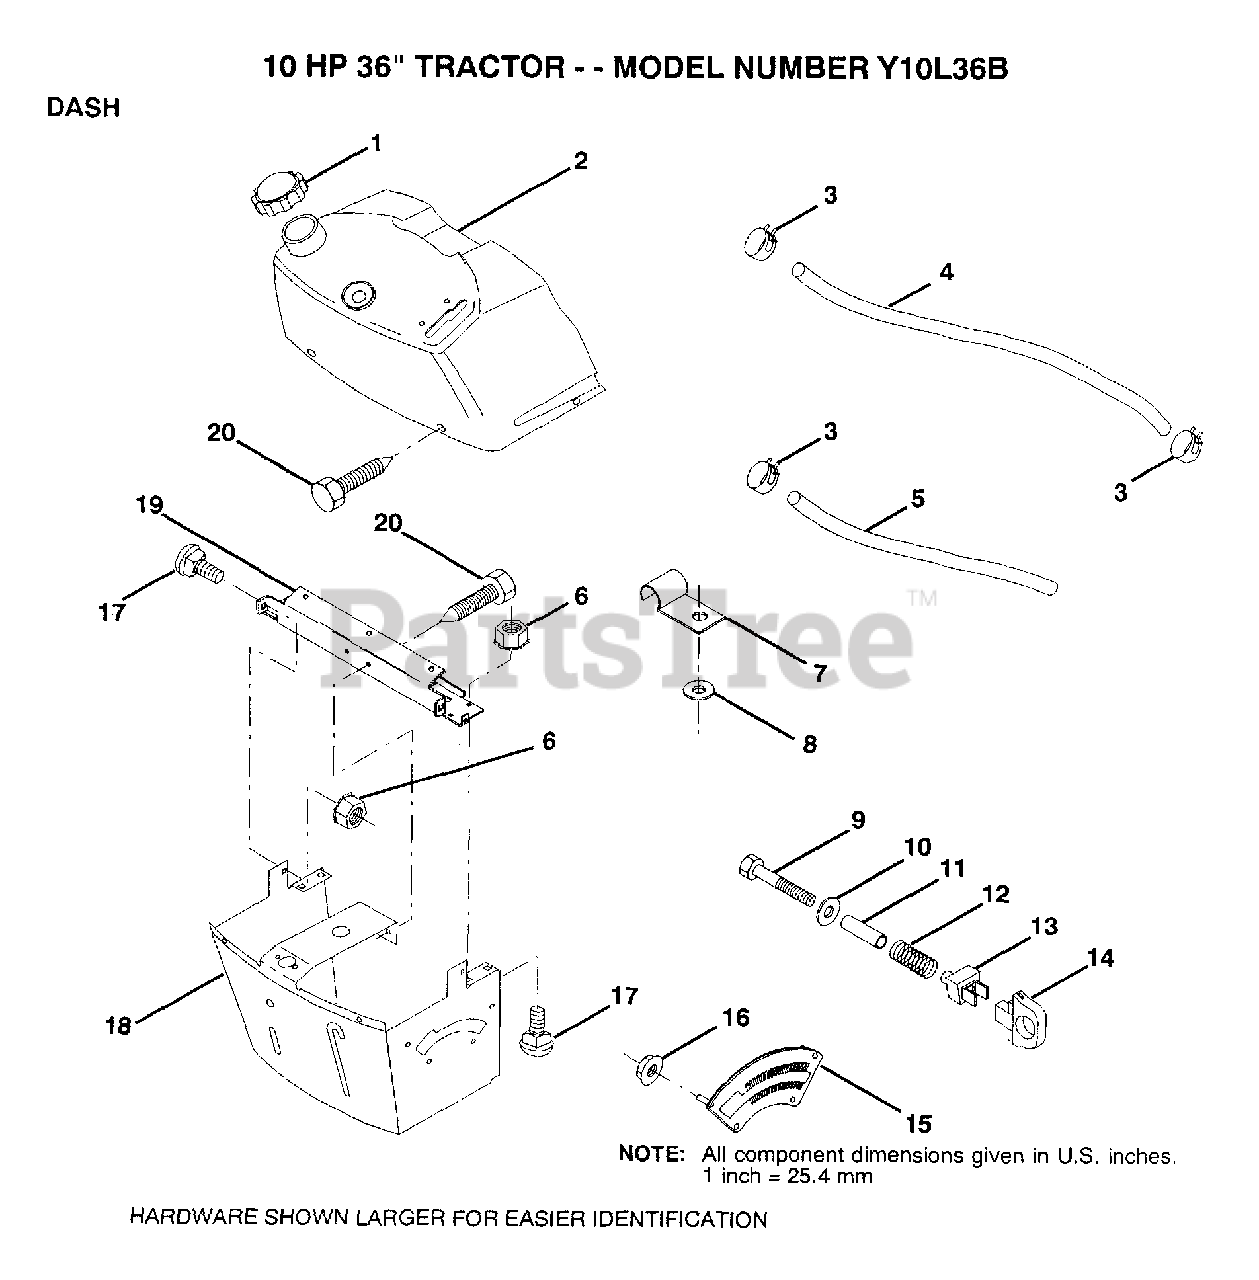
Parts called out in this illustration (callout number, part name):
1	CAP.FUEL.N/VENT
2	TANK.ASM.DASH.LR
3	HOSE CLAMP
5	FUEL LINE T
6	NUT
7	CLIP T
8	WASHER PM
9	BOLT
11	SPACER SPLIT
12	SPRING M
13	"KNOB,HGT RETAINER"
14	KNOB
15	ADJUSTER QUAD
16	NUT
17	BOLT
18	SUPT ASSY DASH
19	CROSS BRACE
20	SCREW.1/4-20X1/2
